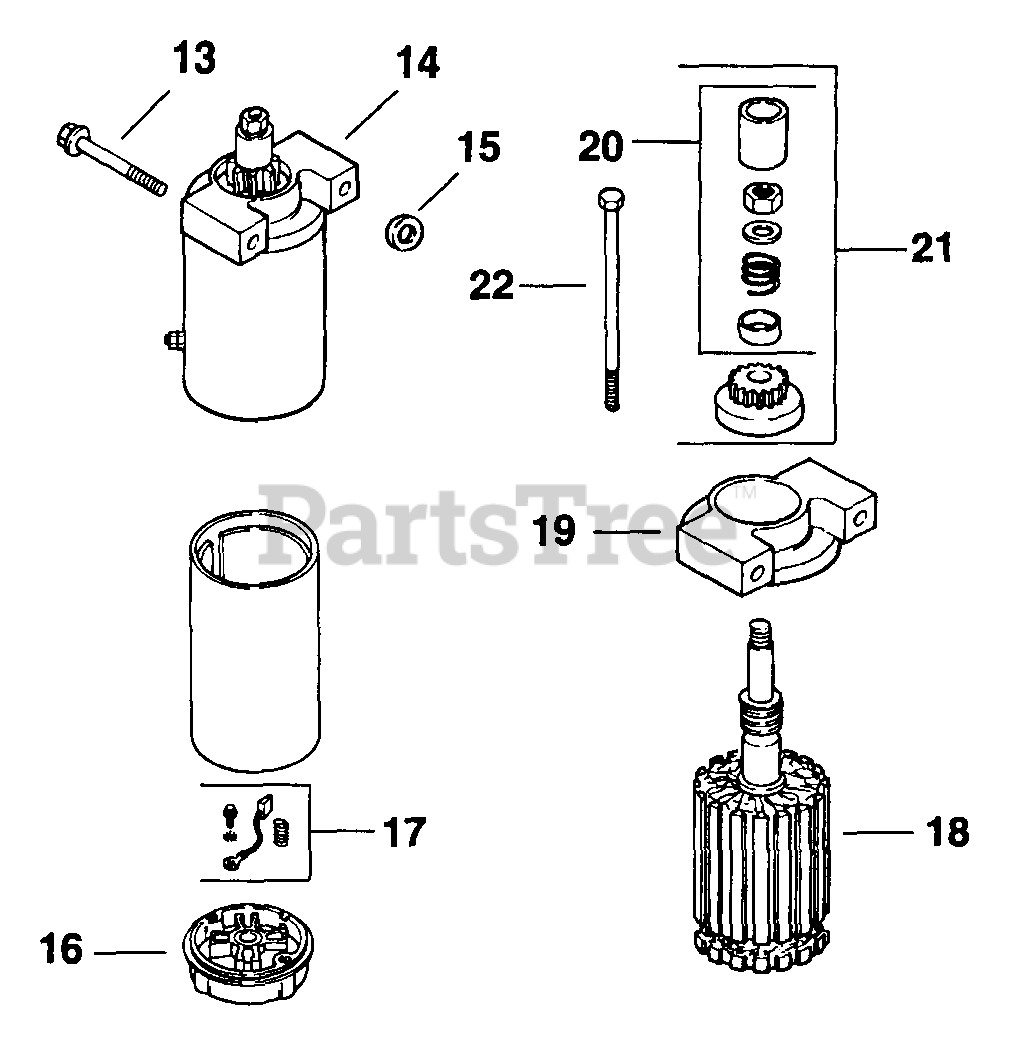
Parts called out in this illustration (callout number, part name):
13	SCREW - USE M-839070
14	STARTER - USE 12 098 13
15	WASHER, FLAT 11/32"
16	CAP - USE 12 227 11
17	KIT - USE 82 755 28
18	ARMATURE - DISCONTINUED
19	CAP - USE 12 227 05
20	DRIVE KIT - USE 12 755 53
21	DRIVE KIT - USE 12 755 53
22	SCREW - DISCONTINUED
